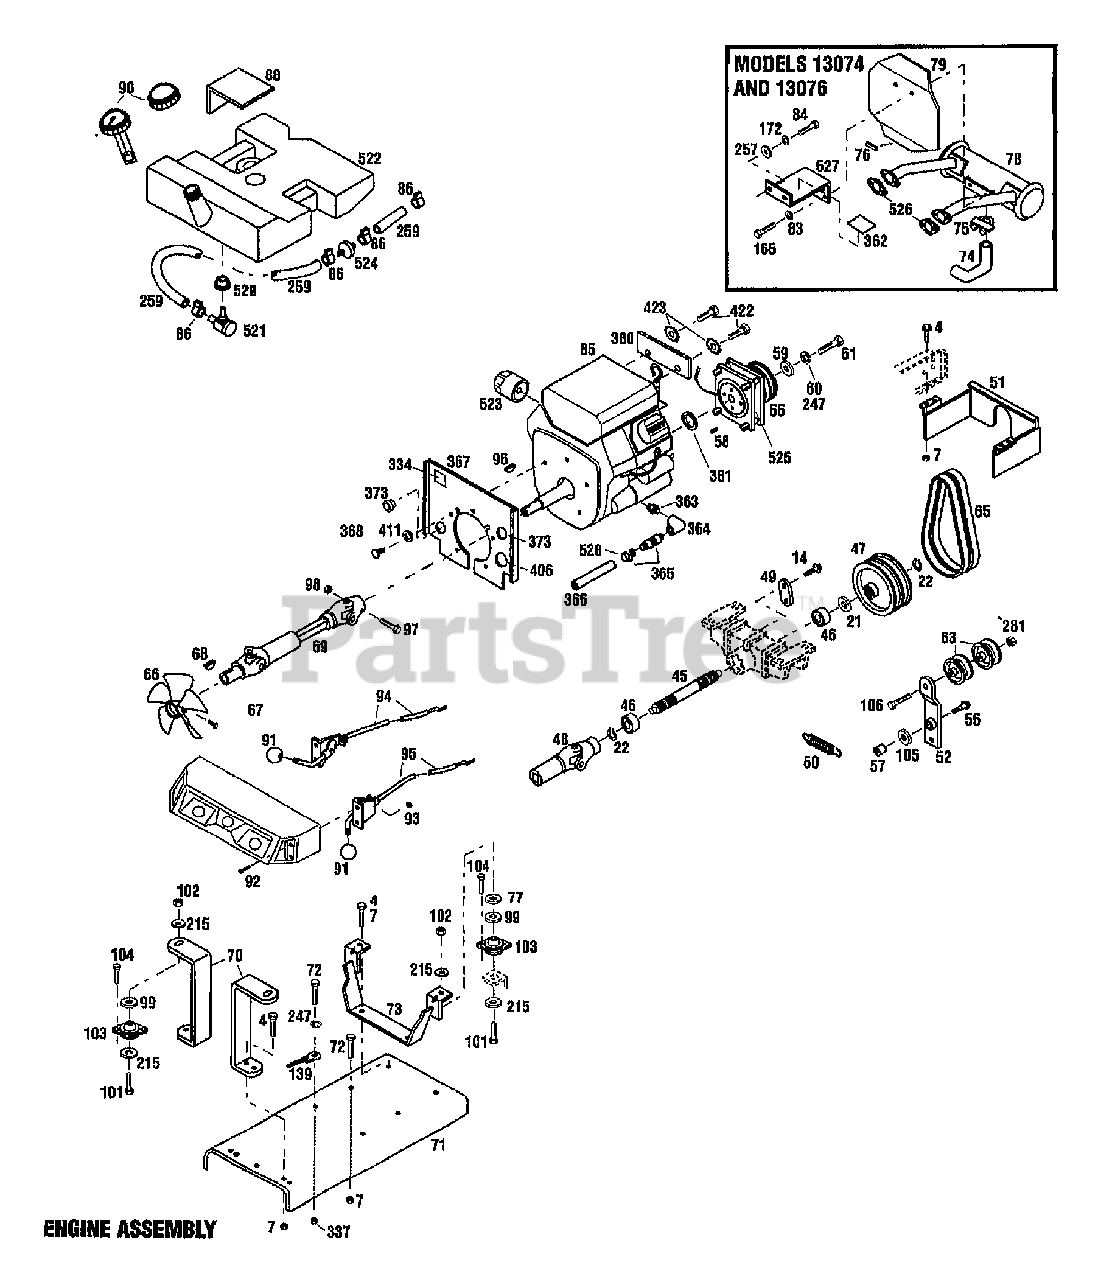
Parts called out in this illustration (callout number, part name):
7	NUT-HFLK 3/8-16 ZP
14	SCR-HFLK 5/16-18X.75 ZP
21	WASHER-THRUST
22	RING-HEAVY EXT HD 1.0 ID
45	SHAFT-PTO
46	BEARING-BALL
47	SHEAVE-PTO
48	JOINT-UNIVERSAL
49	ANCHOR-SPRING
51	GUARD-PTO
52	ARM-IDLER
55	PTO CLUTCH
56	HEX SCREW
57	BUSHING
57	BALL BEARING
59	WASHER-1.7X.453X.25
60	WASHER-LK .438 ZP
61	SCR-HH 7/16-20X1.25 G5ZP
63	PULLEY-IDLER
65	BELT-V (SET OF 2)
67	BOLT-SQUARE HD SET
68	KEY-WOODRUFF .188X.75
69	SHAFT-DRIVE
70	SUPPORT-REAR BAR
71	PLATE-ENGINE MOUNTING
72	SCR-HFLK 3/8-16X1.50
73	SUPPORT-FRONT ASSM
74	PIPE-EXHAUST
75	CLAMP-MUFFLER
77	WASHER-1.5X.375X.18 ZP
78	MUFFLER
79	SHIELD-HEAT
83	WASHER-LK .25 ZP
84	BOLT M8X20
85	ENGINE, KOHLER 18 HP PS-551084
85	ENGINE, KOHLER 18 HP PS-62542
85	ENGINE, KOHLER 20 HP PS-251776
85	ENGINE, KOHLER 20 HP PS-64549
86	CLAMP-HOSE
88	PAD-FUEL TANK
90	CAP-FUEL
91	KNOB
93	NUT W/LKWASHER 10-24 ZP
94	CONTROL-CHOKE
95	CONTROL-THROTTLE
96	KEY-WOODRUFF .25X.875
97	SCR-HH 1/4-20X2.0 G5 ZP
98	NUT-HT LK 1/4-20
99	WASHER
101	SCR-HH 3/8-16X2.25 G5 ZP
102	NUT-LOCK 3/8-16
103	MOUNT-FRONT
105	WASHER-1.115X.637X.06
106	SCR-HH 3/8-16X2.25 G5 ZP
139	CABLE-BATTERY NEGATIVE
165	SCR-HH M6-1.0X19MM
172	WASHER-LK .312 ZP
215	WASHER-FLAT 1.25X.406X.179
247	WASHER-LK .375 @ DEPL
257	WASHER-FLAT 5/16 SAE
259	FUEL LINE
281	SCR-HXSKT 5/16-18X.75 BO
334	DECAL-WARNING
337	NUT-HEX 3/8-16 ZP
362	DECAL-HOT SURFACE
363	FITTING-3/8 NPT HEX NIPPLE
364	ELBOW-3/8 NPT 90 DEGREES
365	ASSM-OIL VALVE
366	HOSE-DRAIN
367	SHIELD-HEAT W/DECAL
368	CLIP
373	GROMMET-SNAP BUSHING
380	CLUTCH-STOP
381	SPACER-CRANKSHAFT
406	BUSHING
411	WASHER-LK INTERNAL TOOTH 1/4
423	EXTERIOR TOOTH LOCK WASHER
520	BUSHING-RUBBER
521	VALVE-SHUT OFF
522	ASSM-FUEL TANK
523	OIL FILTER
524	FILTER-FUEL
525	COIL-CLUTCH FIELD
526	MUFFLER GASKET
527	BRACKET-MUFFLER
528	CAP-OIL DRAIN
